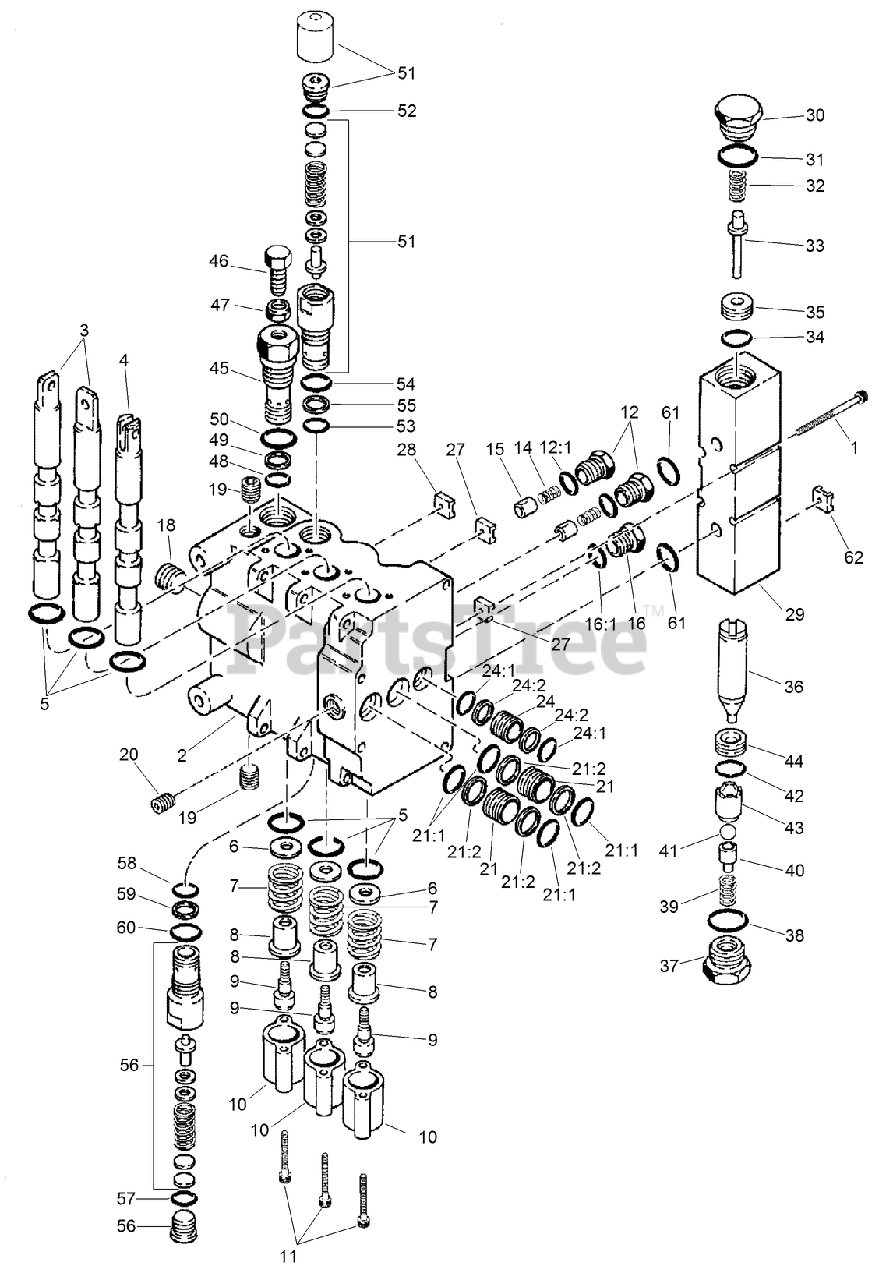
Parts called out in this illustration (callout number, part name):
2	Body-Valve
3	SPOOL-CONTROL, DUAL
4	SPOOL-STABLILIZER
5	O-RING
6	WASHER-FLAT
7	SPRING-RETURN
8	SPACER-spring
9	BOLT-SHOULDER
10	Cap-End
12	PLUG ASM
14	SPRING-poppet
15	POPPET-CHECK, LOAD
16	PLUG ASM
18	PLUG-HEX SOCKET, PIPE
19	PLUG
20	PLUG-SEAL
21:1	O-RING
21:2	RING-BACKUP
24:2	RING-BACKUP
29	BODY-CHECK, PILOT
31	O-RING
35	SEAT-PILOT
36	PLUNGER
38	O-RING
41	BALL-STEEL
43	RETAINER
44	SEAT-PILOT
45	Valve-Relief
49	RING-BACKUP
51	Valve-Relief
54	O-RING
55	RING-BACKUP
56	Valve-Relief
59	RING-BACKUP
60	O-RING
62	ORIFICE
